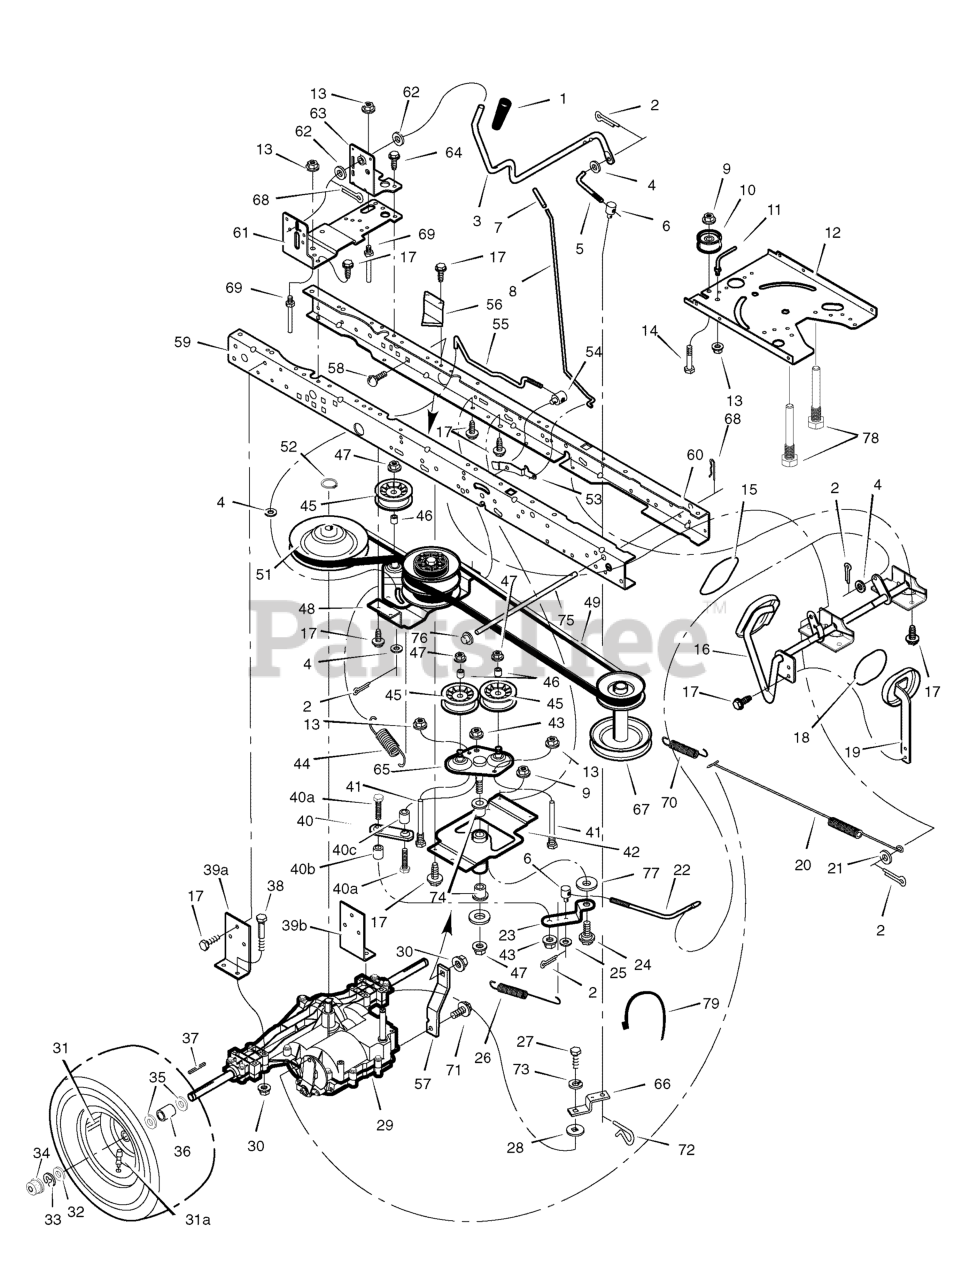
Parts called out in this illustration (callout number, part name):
1	Grip, Shift
2	Pin, Cotter
3	Lever, Shift
4	Washer
5	Link, Shifter
6	Nut, Adjuster
8	Rod, Parking Brake
9	Nut
10	Pulley, Idler
11	Guide, Belt
12	Plate, Steering
13	Nut
14	Bolt, Hex
15	Pad, Motion Drive
16	Assembly, Speed Control
17	Screw, Self Tapping
18	Pad, Brake Pedal
19	Assembly, Brake Pedal
20	Spring, Extension
21	Washer
22	Rod, Speed Control
23	Bellcrank
24	Bolt, Shoulder
26	Spring, Extension
27	Screw, Cap
29	Transaxle **
30	Nut
31	Assembly, Wheel and Tire
37	Key, Square
38	Bolt, Hex
40	Link, Variator
41	Guide, Belt
42	Bracket, Front Frame
43	Nut, Lock
44	Spring, Extension
47	Nut
48	Assembly, Variator and Idler
49	Belt, Primary
50	Belt, Secondary
51	Pulley, Transaxle
52	Ring, Snap
53	Latch, Parking Brake
54	Nut, Adjusting
55	Rod, Clutch
56	Bracket, Brake
57	BRACKET, Torque Strap, LH
58	Screw
59	Rail, Right Frame
60	Rail, Left Frame
61	Bracket, Right Shift
62	Washer
63	Bracket, Shift Pivot
65	Assembly, Idler
66	Yoke, Shift
67	Pulley, Stack
68	Pin, Hair
69	Guide, Belt
70	Spring, Return
72	Pin, Hair
75	Rod, Belt Guide
76	Nut, Push-On
77	Washer
78	Guide Screw
79	Tie Strap
